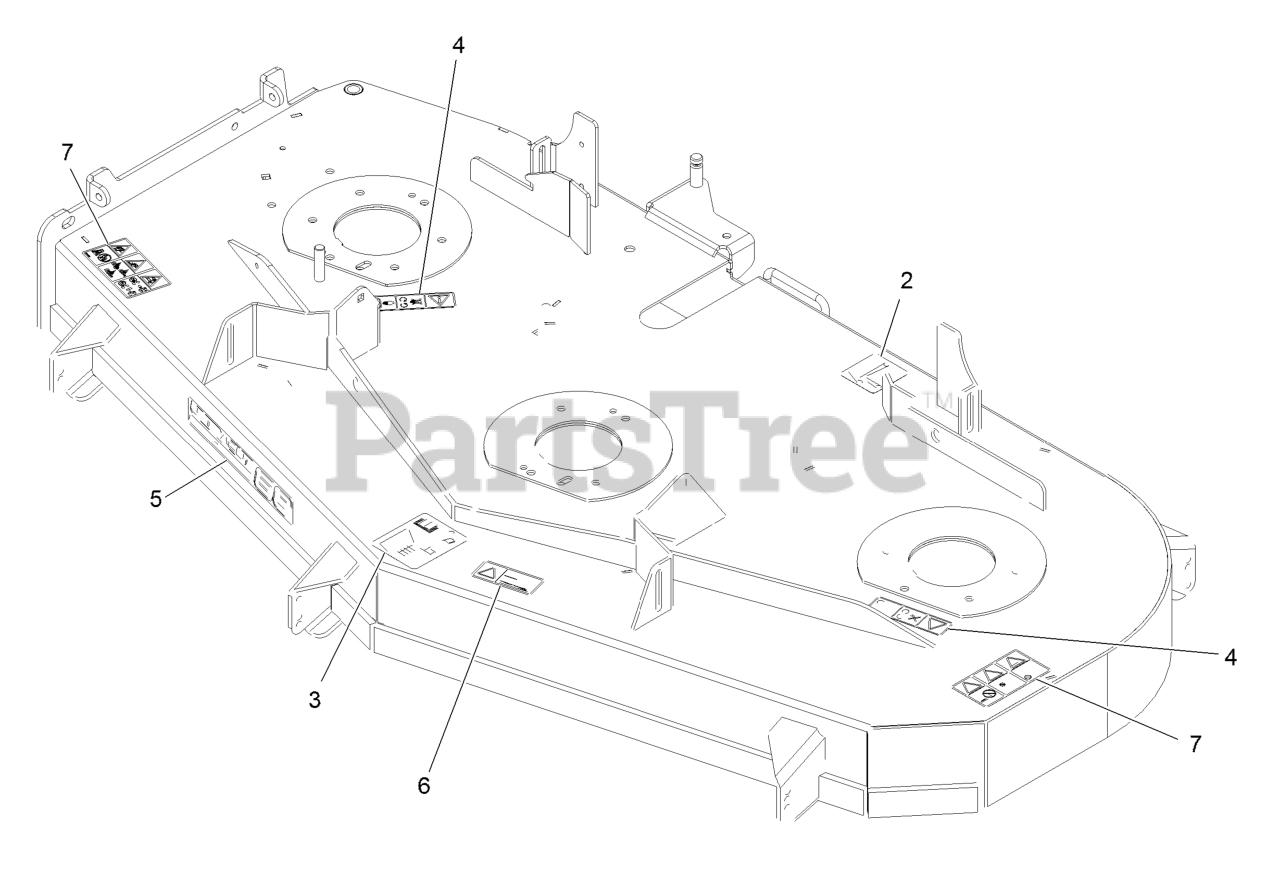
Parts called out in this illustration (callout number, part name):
2	Decal-Routing, Belt
3	Decal-Roller, Anti-Scalp
4	Decal-Cover, Missing
5	Decal-Ultracut 60 Series 3
6	Decal-Bolt Torque
7	Decal-Danger Thrown Objects
